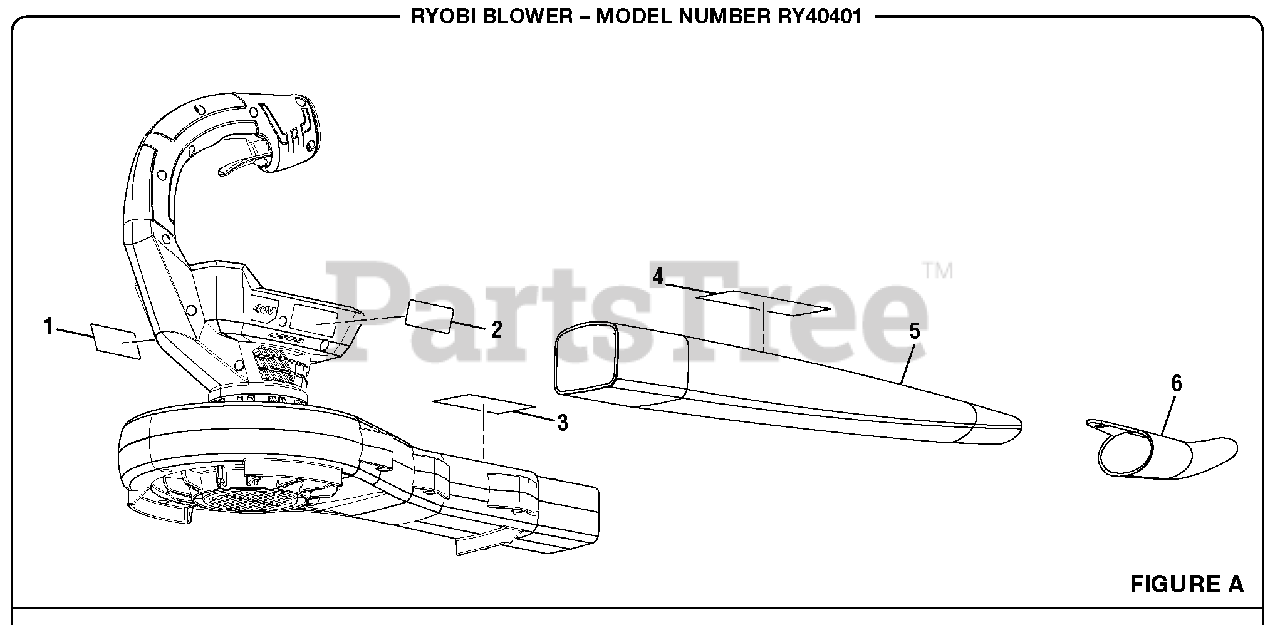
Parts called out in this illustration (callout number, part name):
1	Logo Label
2	Data Label
3	Icon Warnings Label
4	Tube Logo Label
5	Blower Tube
6	High Speed Nozzle
